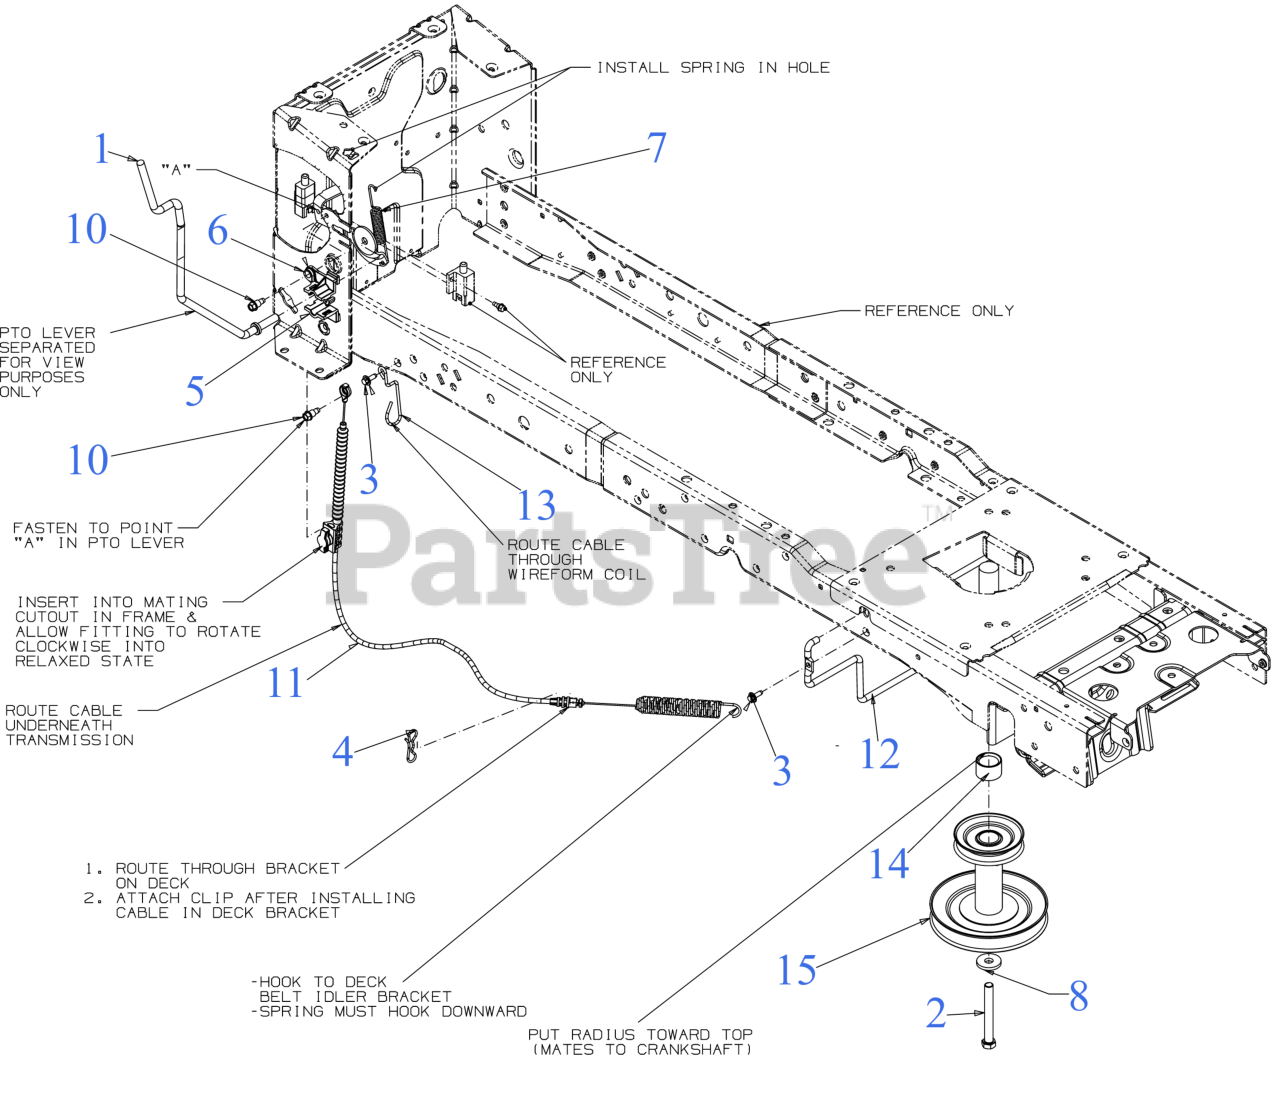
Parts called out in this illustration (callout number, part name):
1	PTO HANDLE ASSEMBLY
2	SCREW 7/16-20 x 3.5 GR5
3	SCREW M6-1 x .625
4	BOW TIE COTTER PIN
5	PTO HANDLE BOTTOM BEARING
6	PTO HANDLE TOP BEARING
7	EXTENSION SPRING .56 OD x 4.52
8	FLAT WASHER .445 x 1.248 x .170
10	SHOULDER SCREW
11	PTO HANDLE CABLE
12	BELT KEEPER ROD
13	CABLE GUIDE WIRE
14	ENGINE PULLEY SPACER
15	ENGINE PULLEY (3.56 x 6.12 DIA)
